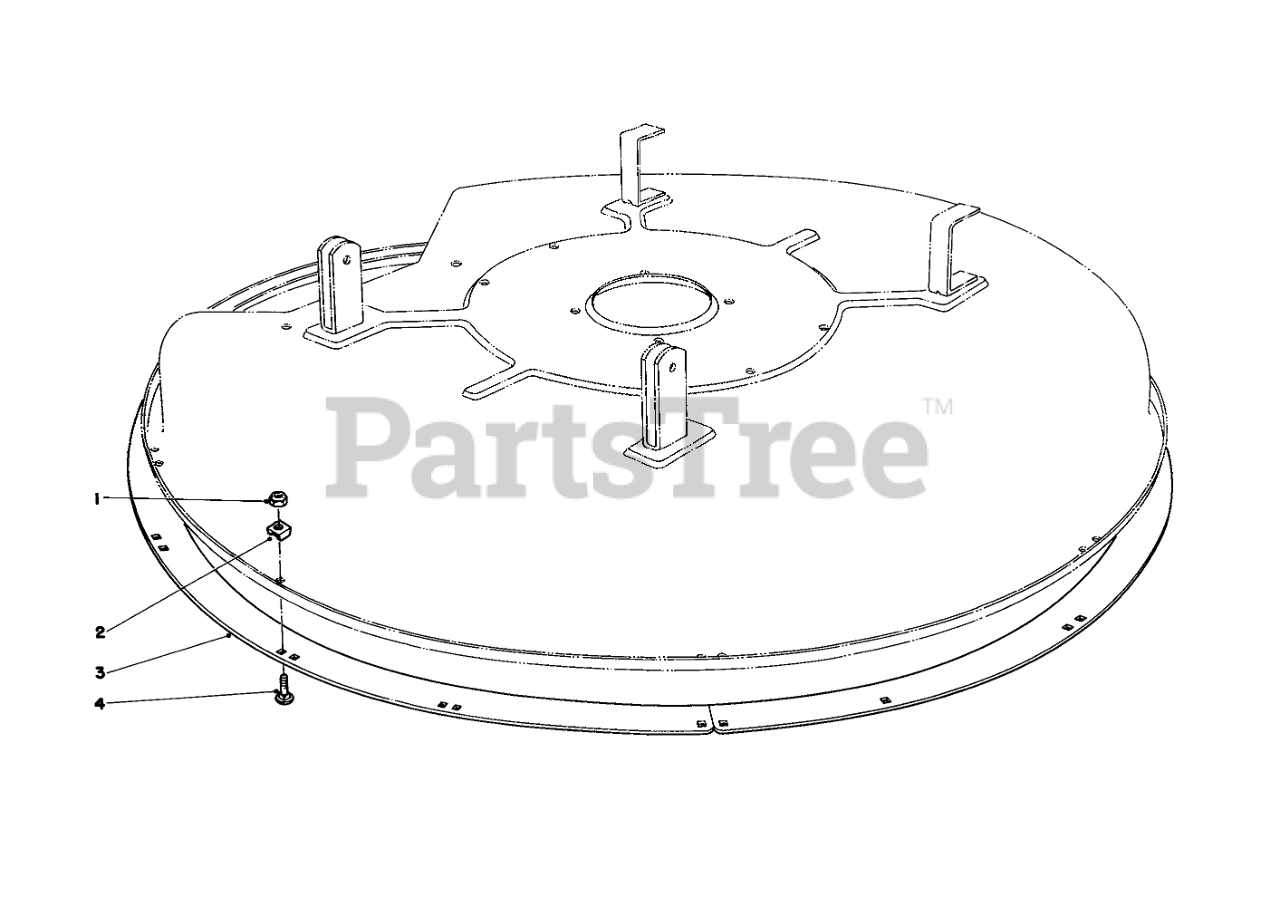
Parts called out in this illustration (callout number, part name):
1	NUT-LOCK, NI
2	DECK RING SPACER
3	DECK RING B
4	BOLT-CARR
